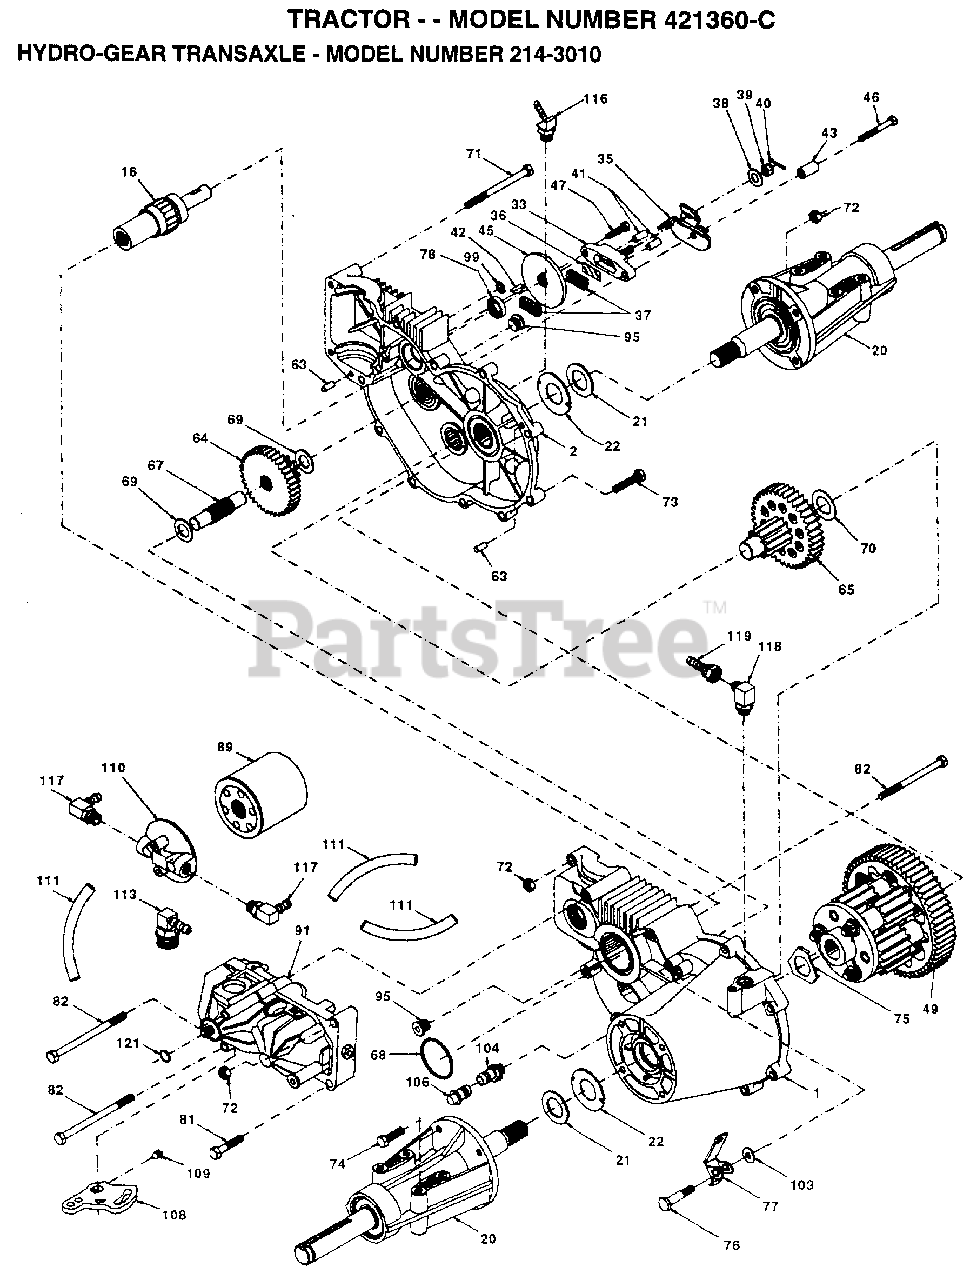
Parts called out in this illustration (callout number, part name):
1	HOUSING LH 70086
2	HOUSING RH 70088
16	SHAFT BRAKE 62877
20	AXLE MTG 70087
21	WASHER 44805
22	WASHER 44806
33	YOKE.BRAKE.62589
35	ARM BRAKE 50214
36	PUCK PLATE 44134
37	PUCK BRAKE 44132
38	WASHER HYD 44130
41	PIN BRAKE 44127
42	KEY HI PRO 44143
43	SPACER 50259
45	DISC BRAKE 44090
46	BOLT 1/4-20 44276
47	BOLT 1/4-20 44433
49	DIFFERENTIAL62834
63	PIN DOWL 44757
64	GEAR R14-38 44775
65	PINION DRIV 70051
67	SHAFT-44779
68	O RING 44781
69	WASHER 44795
70	WASHER 44794
71	BOLT 5/16 44827
72	NUT HXLK 43064
73	BOLT 5/16 44841
74	SCREW 5/16 45089
75	WASHER DIF 44880
76	BOLT SHOULD 44785
77	ARM FREEWHL 44786
78	SEAL.OIL.44761
81	BOLT 5/16 43084
82	BOLT 5/16 44820
89	FILTER SPIN 50037
95	PLUG.9005110-5600
103	WASHER.50169
104	CAP.VENT.70109
106	O-RING.ASM.70110
108	ARM.CONTROL.45007
109	SCREW.SET.50018.
110	FILTER.HEAD.50207
111	HOSE.5/16.50208.
113	FITTING.SAE.50210
116	FITTING.SAE.50213
117	FITTING.SAE.50249
118	FITTING.MAL.50251
119	FITTING.FEM.50250
121	RING.RET.2003016.
